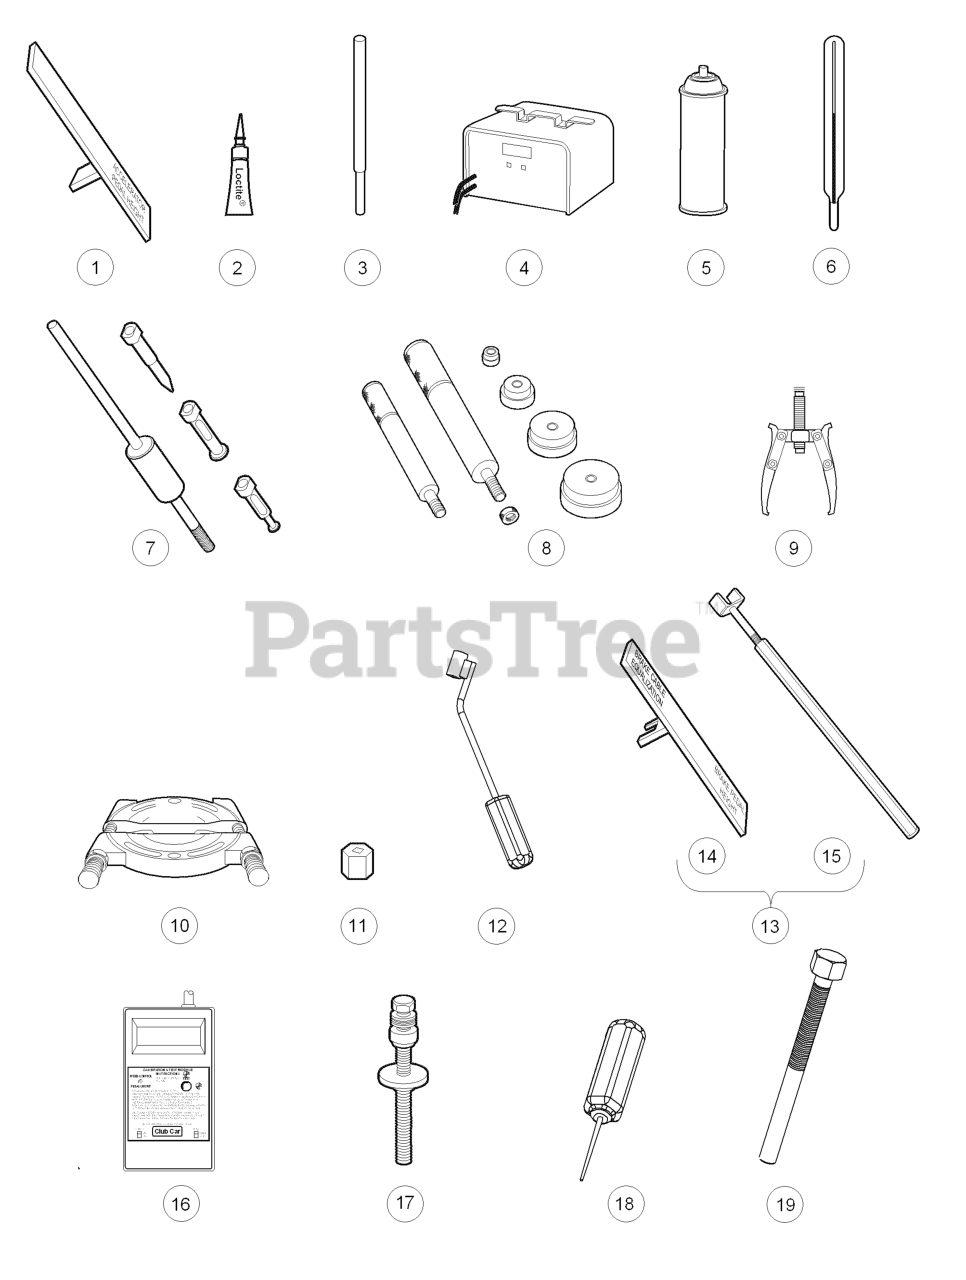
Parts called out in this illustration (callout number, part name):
1	TOOL, ACCEL. PEDAL ADJUSTMENT
2	GUIDE RING ADHESIVE 3 GRAMS
4	BATTERY DISCHARGE UNIT 36/48V
5	BATTERY TERMINAL PROTECT SPRAY
6	BATTERY THERMOMETER
7	BEAR & OIL SEAL REMOVER ASM
8	BEARING DRIVER SET
9	BEARING PULLER
10	BEARING PULLER WEDGE ATTACH.
11	BRAKE ADJUSMENT SOCKET TOOL
12	BRAKE CABLE RELEASE TOOL
13	Brake Pedal Adjustment Tool Kit
14	Brake Pedal Adjustment Tool
15	Brake Pedal Tension Tool
16	CALIBRATION & TEST MODULE
17	CAM INSTALLATION TOOL
18	CHARGER BEZEL TOOL
19	TOOL, REMOVAL, CLUTCH, GAS/DSL
